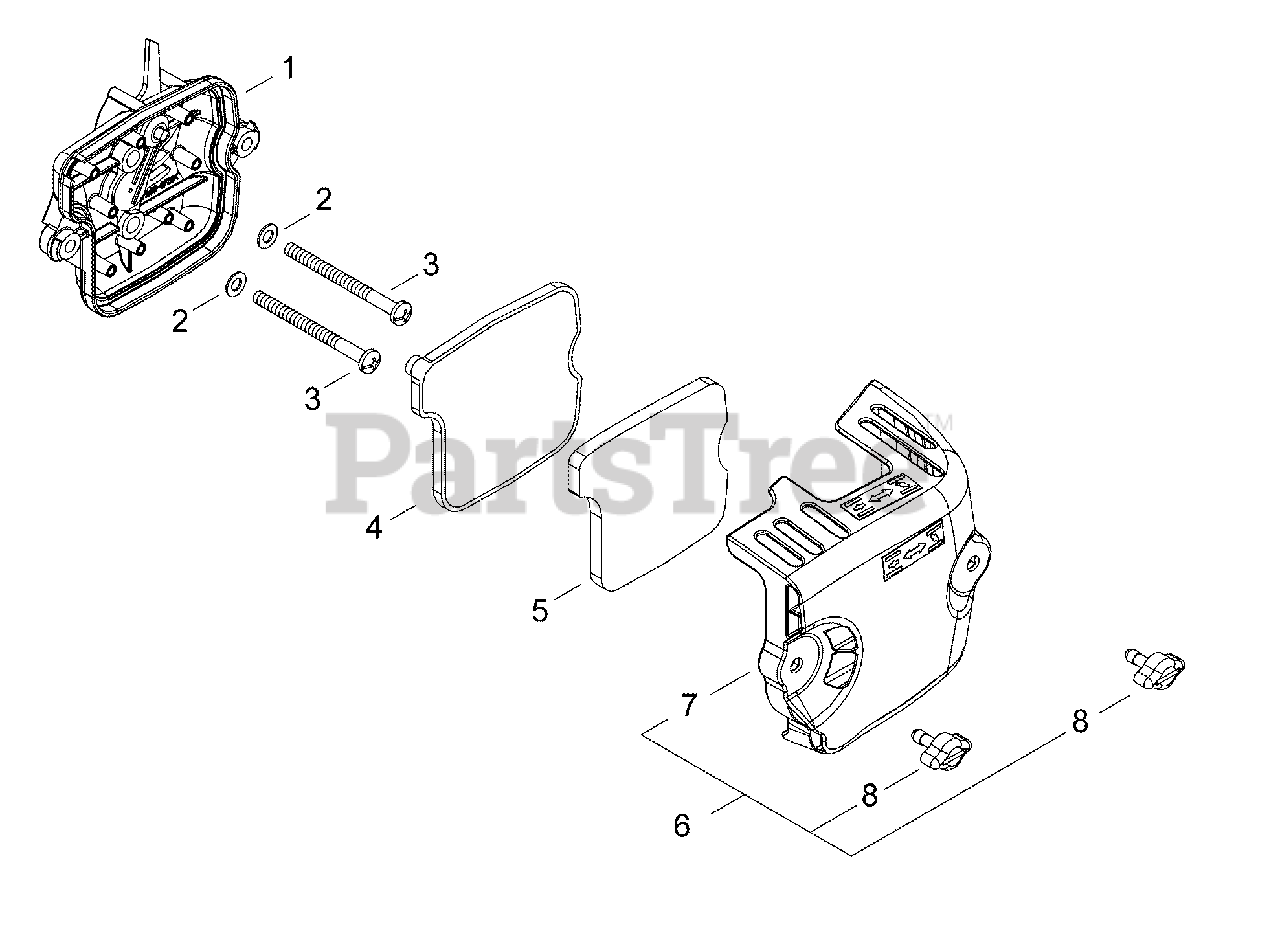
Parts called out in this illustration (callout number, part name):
1	AIR FILTER CASE ASSY
2	WASHER - 5
3	SCREW - 5X60
4	FILTER, AIR
5	PRE-FILTER - FOAM
6	AIR FILTER COVER ASSY
7	COVER, AIR FILTER
8	THUMBSCREW
